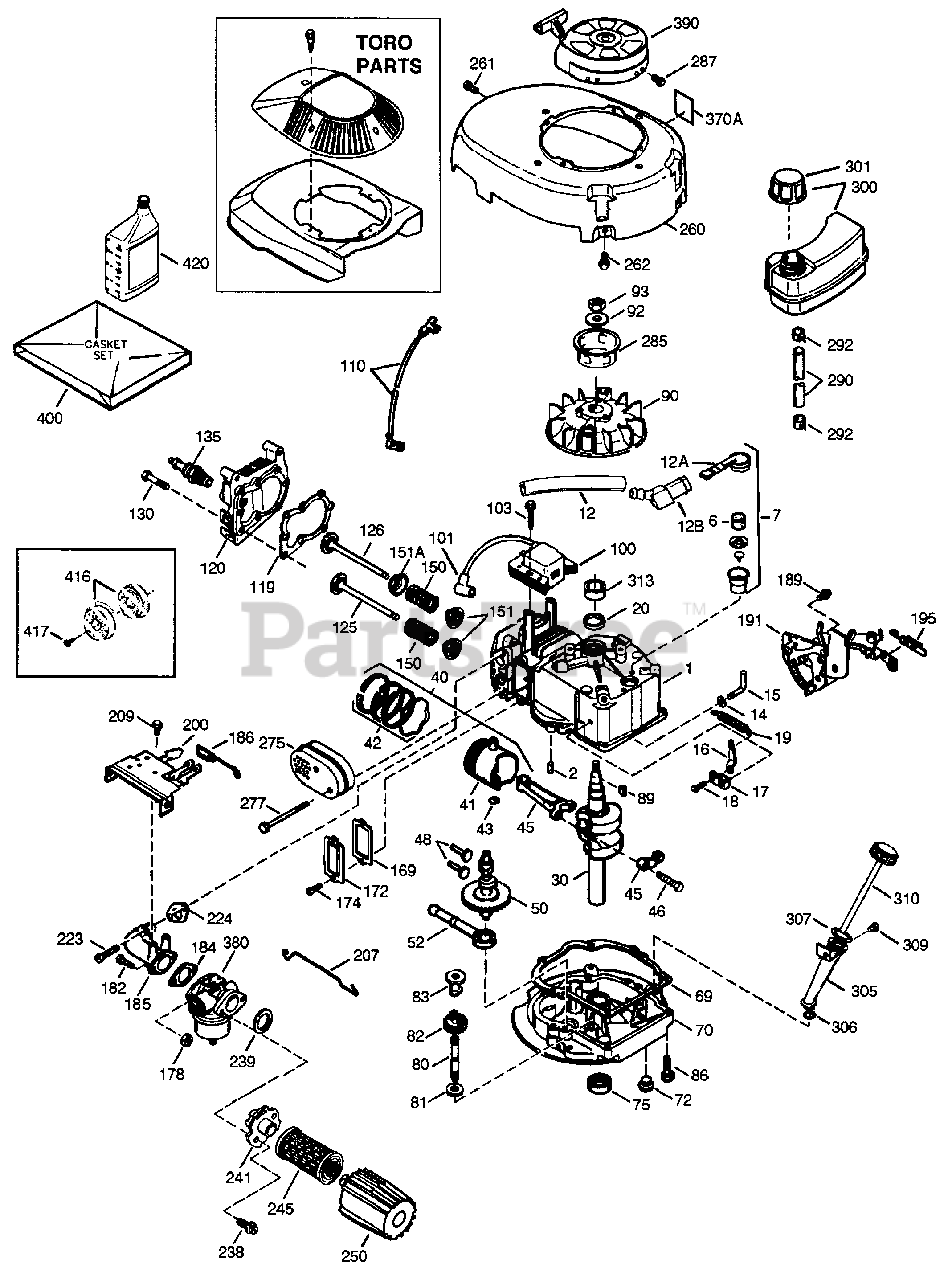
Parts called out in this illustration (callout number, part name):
1	Cylinder (Incl. Ref. #2 & 20)
2	Dowel Pin
6	Breather Element
7	Breather Ass'y (Incl. Ref. #6 & 12A)
12	Breather Tube
12A	Breather Cover & Tube (Incl. Ref. #12B)
12B	Breather Tube Elbow
15	Governor Rod (Incl. Ref. #14)
16	Governor Lever
17	Governor Lever Clamp
18	Screw-Torx T-15
19	Extension Spring
20	Oil Seal
30	Crankshaft
40	Piston, Pin & Ring Set (Std.)
40	Piston, Pin & Ring Set (.010" OS)
41	Piston & Pin Ass'y (Std.)(Incl. Ref. #43)
41	Piston & Pin Ass'y (.010" OS)(Incl. Ref. #43)
42	Ring Set (Std.)
42	Ring Set (.010" OS)
43	Piston Pin Retaining Ring
45	Connecting Rod Ass'y (Incl. Ref. #46)
46	Connecting Rod Bolt
48	Valve Lifter
50	Camshaft (MCR)
52	Oil Pump Ass'y
69	Mounting Flange Gasket
70	Mounting Flange (Incl. Ref. #72-83)
72	Oil Drain Plug
75	Oil Seal
80	Governor Shaft
82	Governor Gear Ass/y (Incl. Ref. #81)
83	Governor Spool
89	Flywheel Key
90	Flywheel
92	Belleville Washer
93	Flywheel Nut
100	Solid State Ignition
101	Spark Plug Cover
103	Screw-Torx T-15
110	Ground Wire
119	Cylinder Head Gasket
120	Cylinder Head
125	Exhaust Valve (Std.)(Incl. Ref. #151)
125	Exhaust Valve (1/32" OS)(Incl. Ref. #151)
126	Intake Valve (Std.)(Incl. Ref. #151)
126	Intake Valve (1/32" OS)(Incl. Ref. #151)
135	Resistor Spark Plug (RJ19LM)
150	Valve Spring
151	Valve Spring Cap
151A	Intake Valve Seal
169	Valve Cover Gasket
172	Valve Cover
178	Nut & Lock Washer
182	Screw
184	Carburetor To Intake Pipe Gasket
185	Intake Pipe
186	Governor Link
191	S.E. Brake Bracket (Incl. Ref. #195)
195	Terminal
200	Control Bracket
207	Throttle Link
224	Intake Pipe Gasket
239	Air Cleaner Gasket
241	Air Cleaner Collar
245	Air Cleaner Filter
250	Air Cleaner Cover
260	Blower Housing
275	Muffler (Incl. Ref. #277)
285	Starter Cup
290	Fuel Line
292	Fuel Line Clamp
300	Fuel Tank (Incl. Ref. #292 & 301)
301	Fuel Cap
305	Oil Fill Tube
310	Dipstick
370A	Lubrication Decal
380	Carburetor (Incl. Ref. #184)
390	Rewind Starter (Note: This engine could have been built with 590739 starter)
400	Gasket Set (Incl. items marked P in notes)(Incl. part #'s 26756, (1) 28833 (1), 36832 (1), 34338 (1), 35261 (1), 36783 (1), 36786 (1), & 36787 (1).
416	Spark Arrestor Kit (Incl. Ref. #417)(Optional)
417	Screw (Optional)
420	SAE 30 4-Cycle Engine Oil (Quart)
